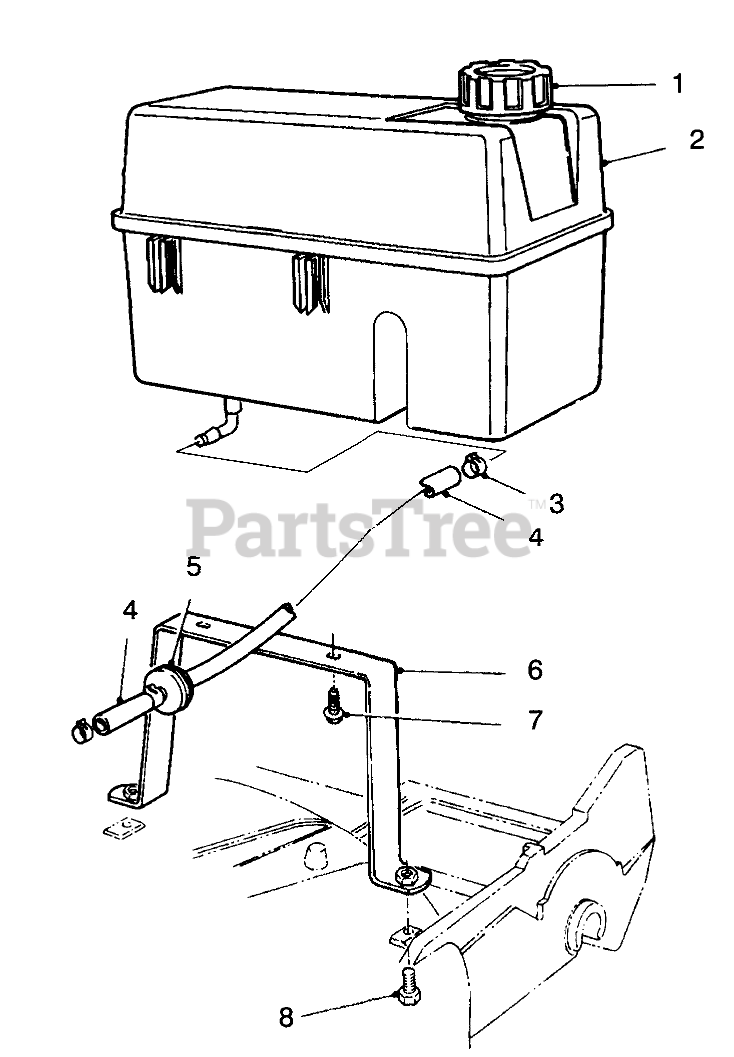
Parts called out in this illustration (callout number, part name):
1	GAS CAP ASM
2	TANK - FUEL
3	CLAMP-FUEL LINE
4	HOSE-FUEL
5	FILTER-FUEL
6	Wa-Base
7	SCREW-HWH
8	SCREW-HH
